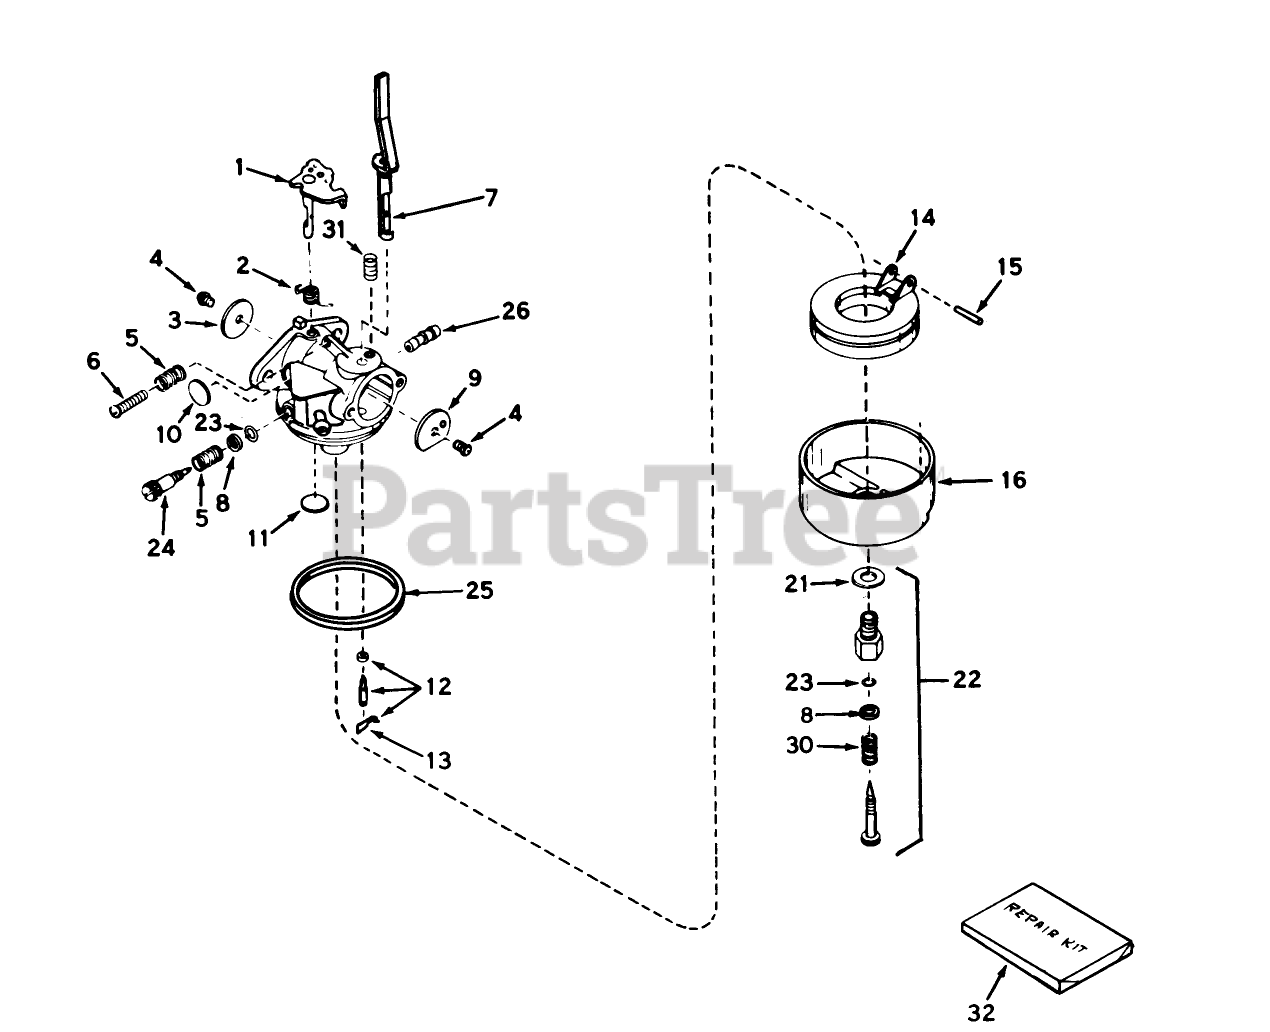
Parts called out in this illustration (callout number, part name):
1	Shaft/Lever-Throttle
2	Spring, Return
3	Shutter-Throttle
4	Screw-Shutter
5	Spring-Tension
6	Screw-Throttle Crack Screw / Idle Speed
7	Shaft Lever Assy., Choke
8	Washer
9	Shutter-choke
10	Plug-Welch, Idle Mixture Well
11	Plug-Welch, Atmospheric Vent
12	Inlet Needle, Seat Clip Assy. (Incl. No. 13)
13	Clip-Spring
14	Float
15	Shaft-Float
16	Bowl-Float (no drain)
21	Washer-Bowl Nut
22	Adjustment Screw Assy., Main (Incl. Nos. 5A, 21 23)
23	ORing
24	Screw, Idle Adj.
25	O Ring-Bowl, Float
26	Fuel Fitting
30	Spring
31	Spring-Positioning, Choke
32	Repair Kit (Incl. items marked *)
